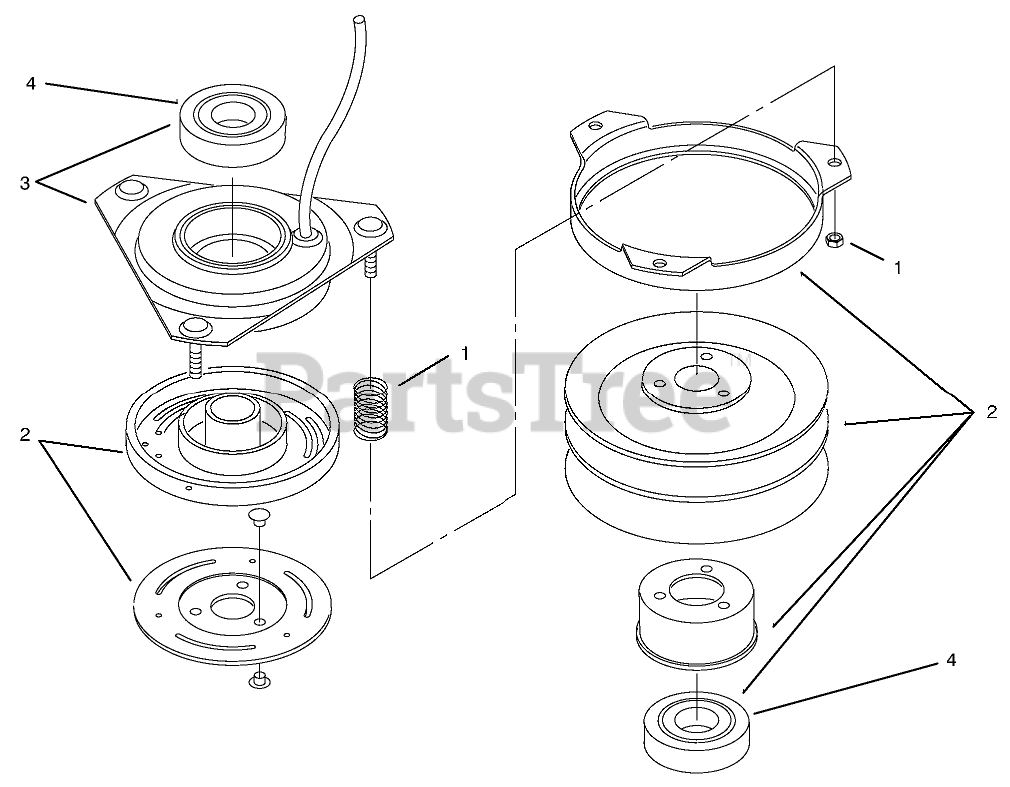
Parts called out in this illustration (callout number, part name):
1	ACCESSORY PKG SRVC PART
2	ASM - ROTOR/ARMATURE
3	FIELD ASSY (SRVC PART)
4	BEARING-ELEC CLUTCH
